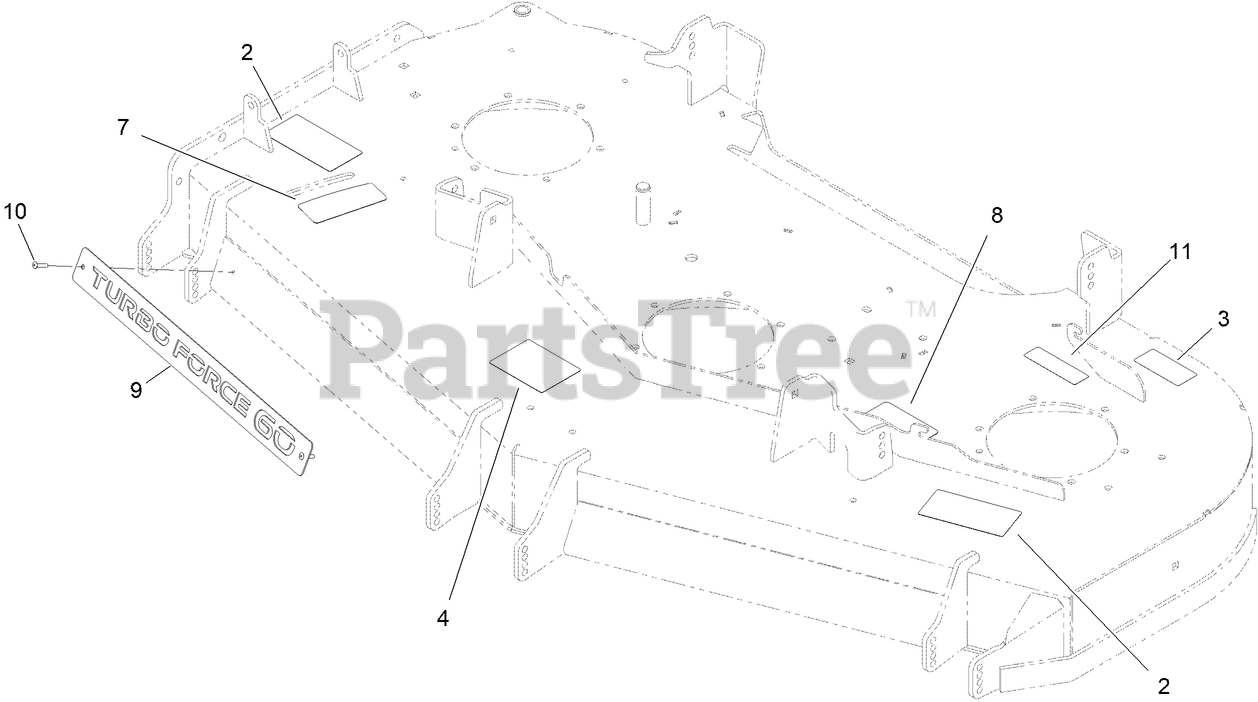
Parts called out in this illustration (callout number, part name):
2	DECAL-DANGER
3	DECAL-BOLT TORQUE
4	DECAL-SCALP, ANTI
7	DECAL - BAFFLE ADJUSTMENT
8	DECAL-BELT ROUTING
9	PLATE-TURBO FORCE [BLACK]
10	RIVET-TRIFOLD
11	DECAL-COVER, MISSING
